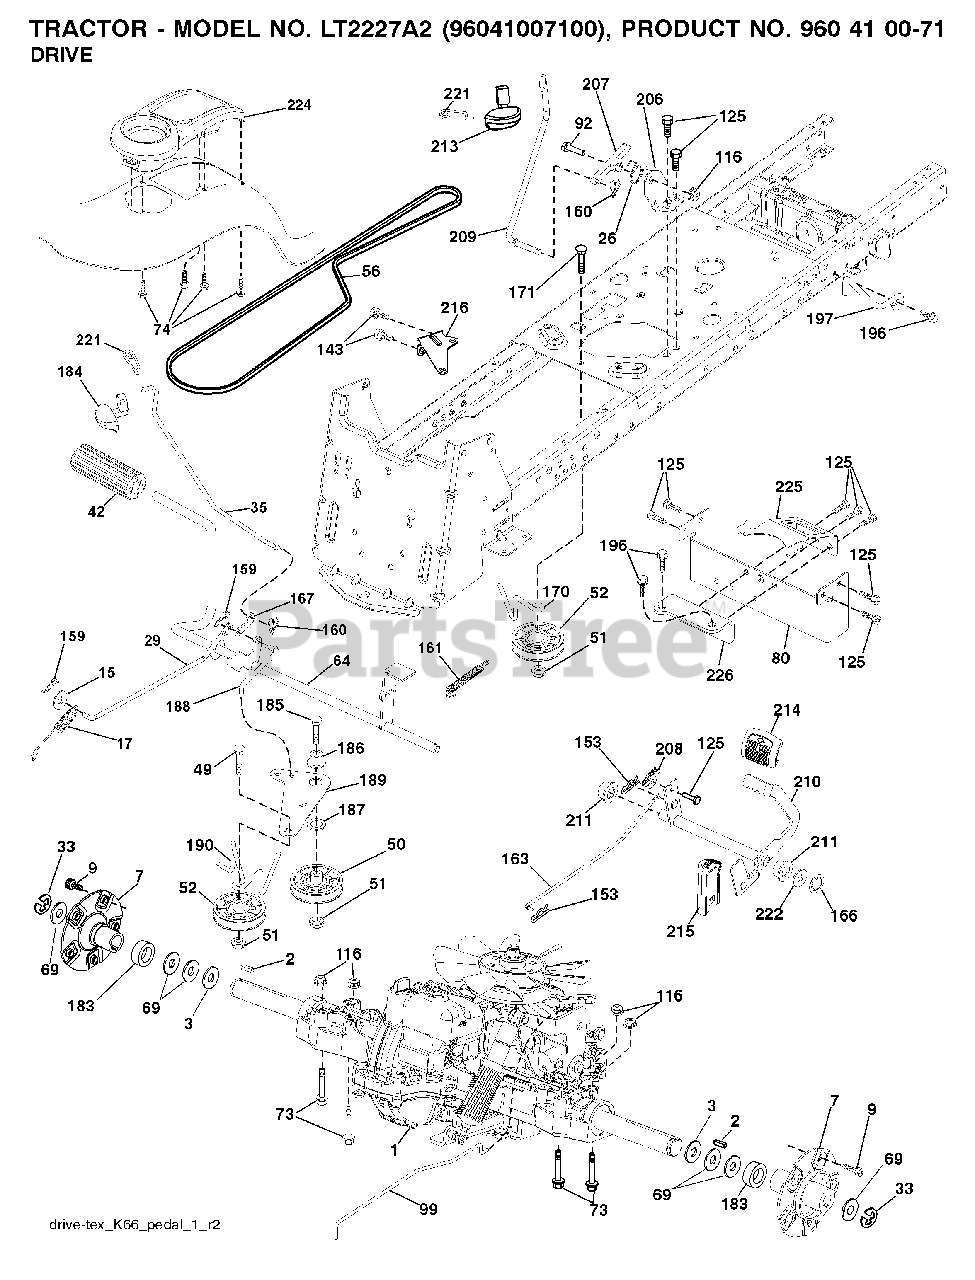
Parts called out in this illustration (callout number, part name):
7	HUB.ASM.WHEEL.REAR.23"TEX
17	SPRING.BRAKE.K46
26	SPRING.RETURN.CRUISE
29	ROD.BRAKE.K66
33	E RING HYT
35	ROD.BRKAE.PARKING.STEALTH
42	PEDAL COVER T
49	BOLT
50	IDLER.FLAT.910.OFFSET
51	NUT LOCK FLG 3/8-16 UNC
52	IDLER.V-GROOVE.910.OFFSET
64	SHAFT.ASM.PEDAL.BRK.CNTR
73	BOLT HEX 5/16-18 GR 5
74	SCREW.HI-LO.CONSOLE
80	STRAP.TORQUE.K66
92	BOLT
99	ROD.SPRING.BYPASS.K66.GT.Z
116	NUT LOCK HEX FLANGE 5/16-18
125	SCREW
153	RETAINER M
159	COTTER PIN
160	RETAINER CLIP
161	SPRING, RETURN LT
163	ROD.PEDAL.CONTROL
166	NUT.PUSH.625.2006
167	LATCH.BRAKE.SPRING
170	KEEPER.V-IDLER.CENTER.
171	BOLT
183	SPACER.AXLE.HG.TEX
184	HANDLE.PRKG.BRAKE.STLTH.TX.RED
186	SPACER.RETAINER
187	WASHER 12/32X2X10GA
188	LINK.CLUTCH.GROUND.DRIVE
189	BELLCRANK.GROUND.DRIVE.TEX.
190	KEEPER.BELLCRANK.DRIVE
196	SCREW 3/8-16X1
197	BRKT.ANIT-ROTATION.CLU
206	BRKT.MOUNT.LATCH.CRUIS
207	LATCH.CONTROL.CRUISE
208	GEAR.SECTOR.CONTROL.CR
209	ROD.CONTROL.CRUISE.STEALTH.TEX
210	ROCKER.ASM.PEDAL.CONTR
211	BEARING.NYLON
213	KNOB.CONTROL.CRUISE
214	PEDAL.FORWARD.TEX.GT.4
215	PEDAL.REVERSE.TEX.GT.4
216	BRACKET.PULLEY.IDLER.W/TEX
221	RETAINER.SPRING.CLIP.H
222	WASHER 21/32 X 1-1/4 X 10 GA.
224	CONSOLE.TOOLBOX.PCH.ERGO.BLACK
225	KEEPER.BELT.TRANSAXLE.K66
226	BRACKET.MOUNT.TORQUE.K66.TG
